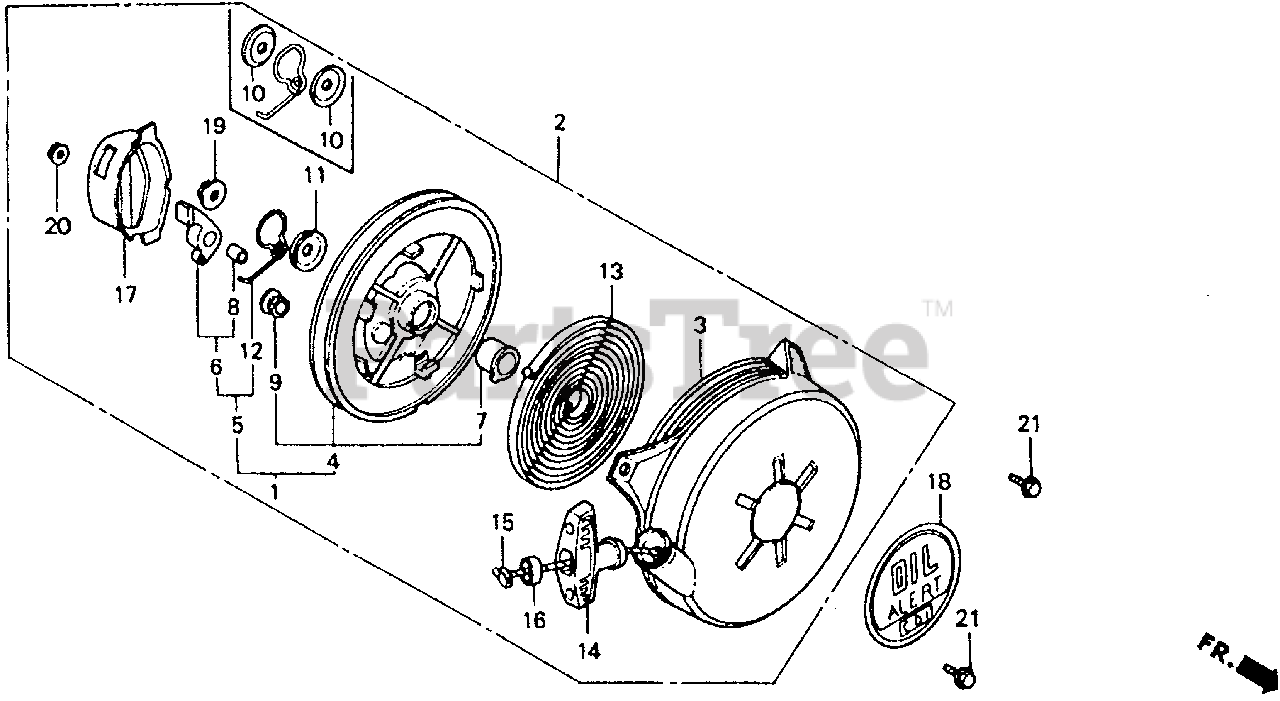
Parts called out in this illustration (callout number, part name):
1	REEL, STARTER
2	STARTER ASSY., RECOIL *R8* (BRIGHT RED)
3	CASE, STARTER *R8* (BRIGHT RED)
4	REEL, STARTER
5	RATCHET KIT
6	RATCHET KIT
6	RATCHET
7	BOSS, REEL
8	BUSH, RATCHET
9	BUSH, REEL STARTER
10	PLATE, FRICTION
11	PLATE, FRICTION
12	RATCHET KIT
12	SPRING, FRICTION
13	SPRING, RETURN
14	GRIP, STARTER
15	ROPE, STARTER (#5X55")
16	SUPPORT, GRIP
17	COVER, REEL STARTER
19	NUT, SELF-LOCK (8MM)
20	NUT, FLANGE (5MM)
21	BOLT, FLANGE (6X8)
